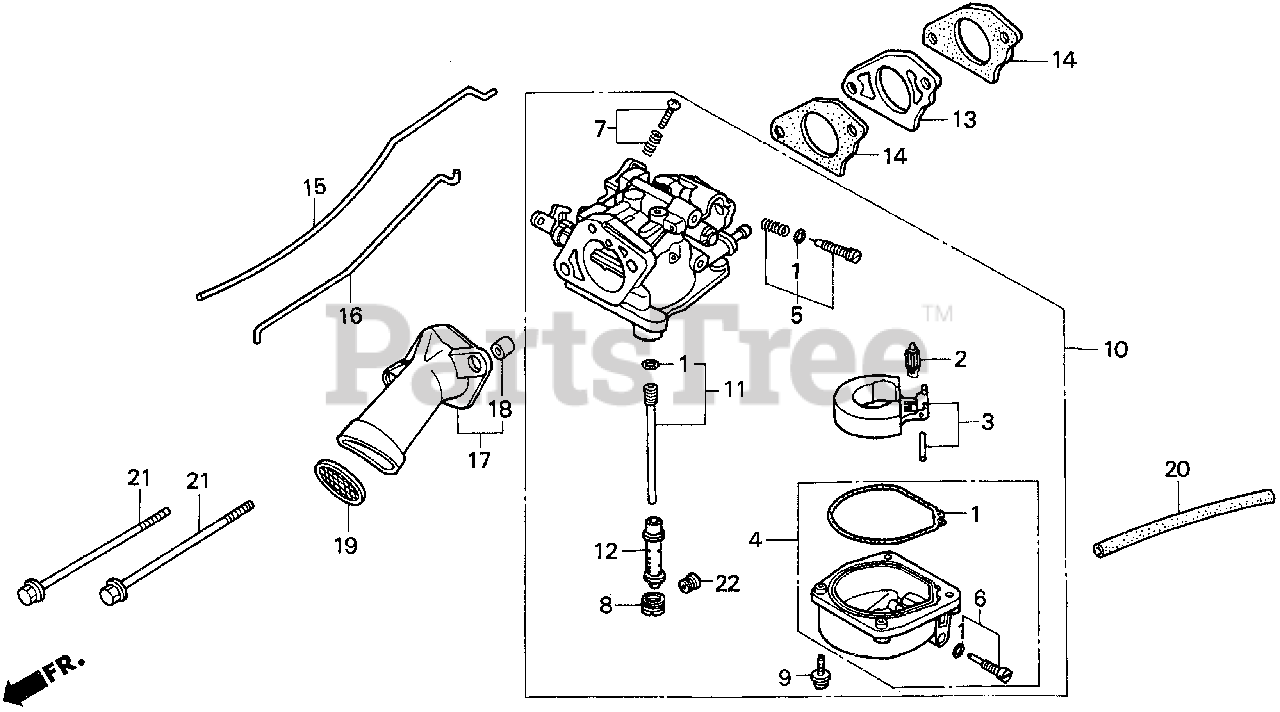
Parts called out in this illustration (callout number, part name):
1	GASKET SET
2	VALVE SET, FLOAT
4	CHAMBER SET, FLOAT
6	SCREW SET, DRAIN
8	SCREW, PLUG
9	SCREW-WASHER
10	CARBURETOR ASSY.
11	JET SET (#48)
12	NOZZLE, MAIN
13	INSULATOR, CARBURETOR
14	GASKET, CARBURETOR
15	ROD, THROTTLE
16	ROD, CHOKE
17	GUIDE, AIR
17	GUIDE ASSY., AIR
18	COLLAR, DISTANCE
19	TRAP, FLAME
20	BULK HOSE, FUEL (3.5X3000) (3.5X100)
20	BULK HOSE, VINYL (3.5X6.5X8000) (3.5X6.5X100)
21	BOLT, FLANGE (6X95)
22	JET, MAIN (#102)
22	JET, MAIN (#98)
22	JET, MAIN (#100)
